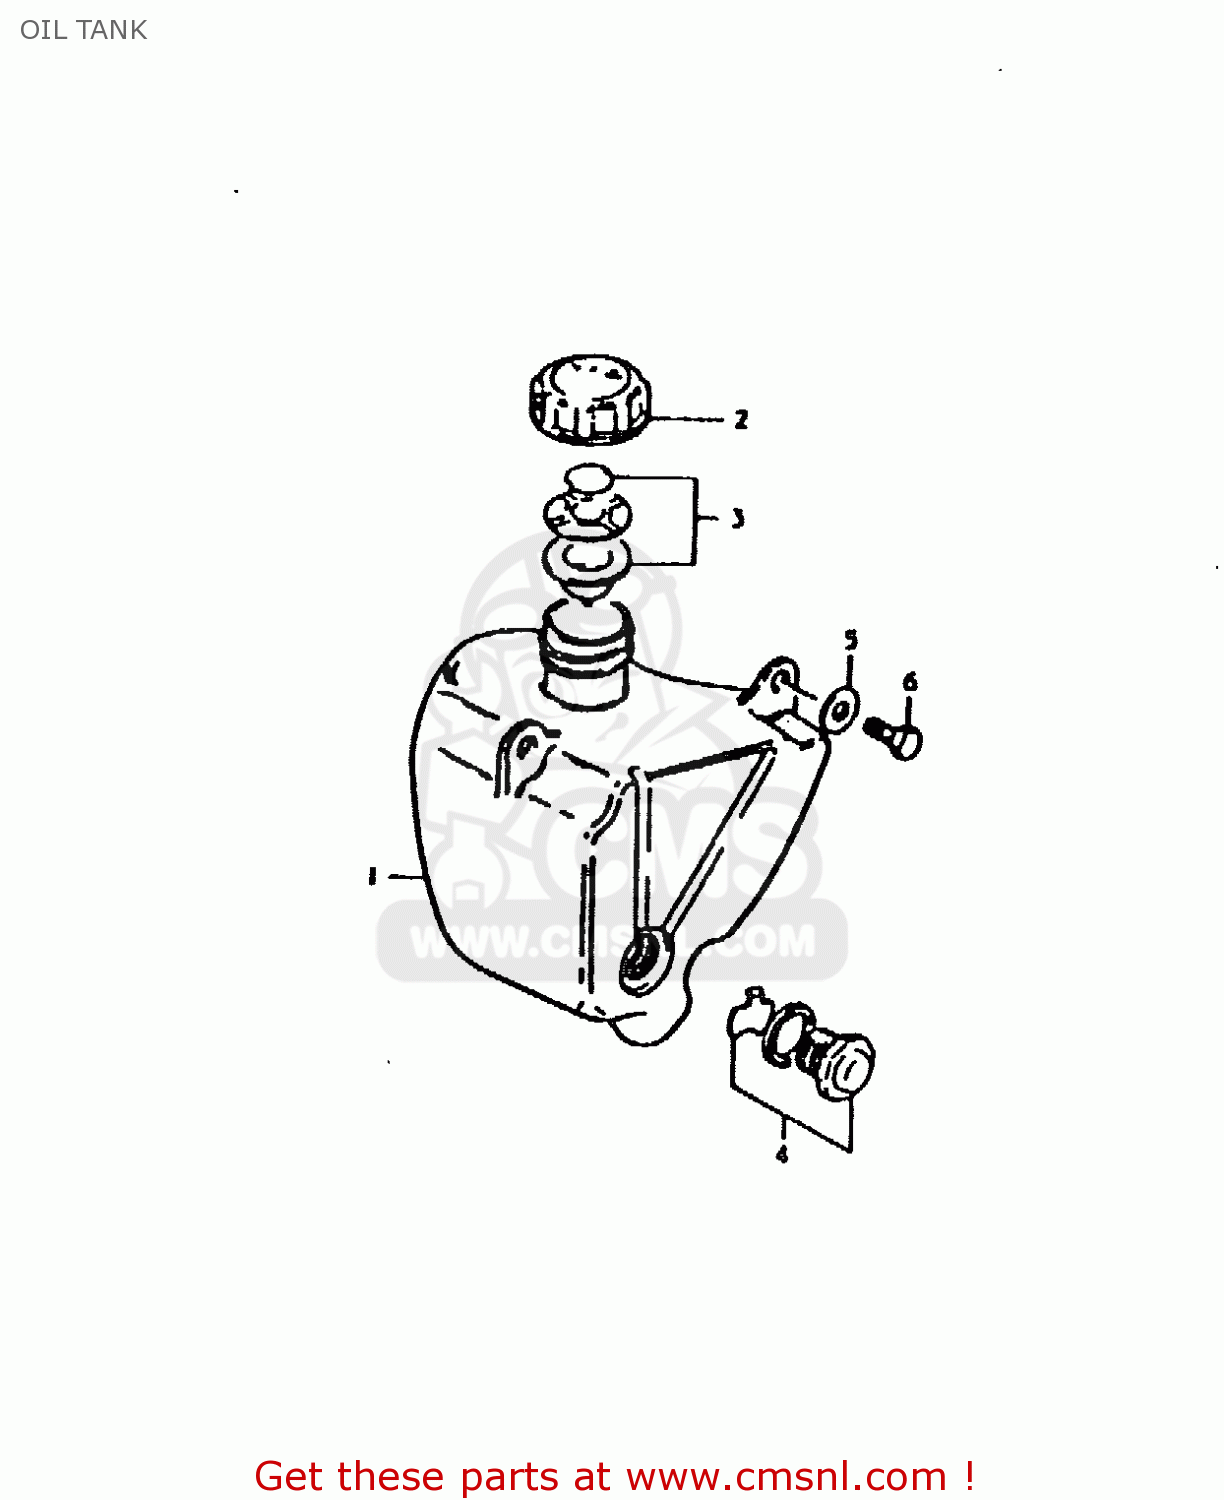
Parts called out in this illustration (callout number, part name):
1	TANK,OIL
2	CAP,OIL TANK
3	GASKET SET (NAS)
4	LENS SET,OIL LEVEL
5	WASHER
6	BOLT, UPPER
